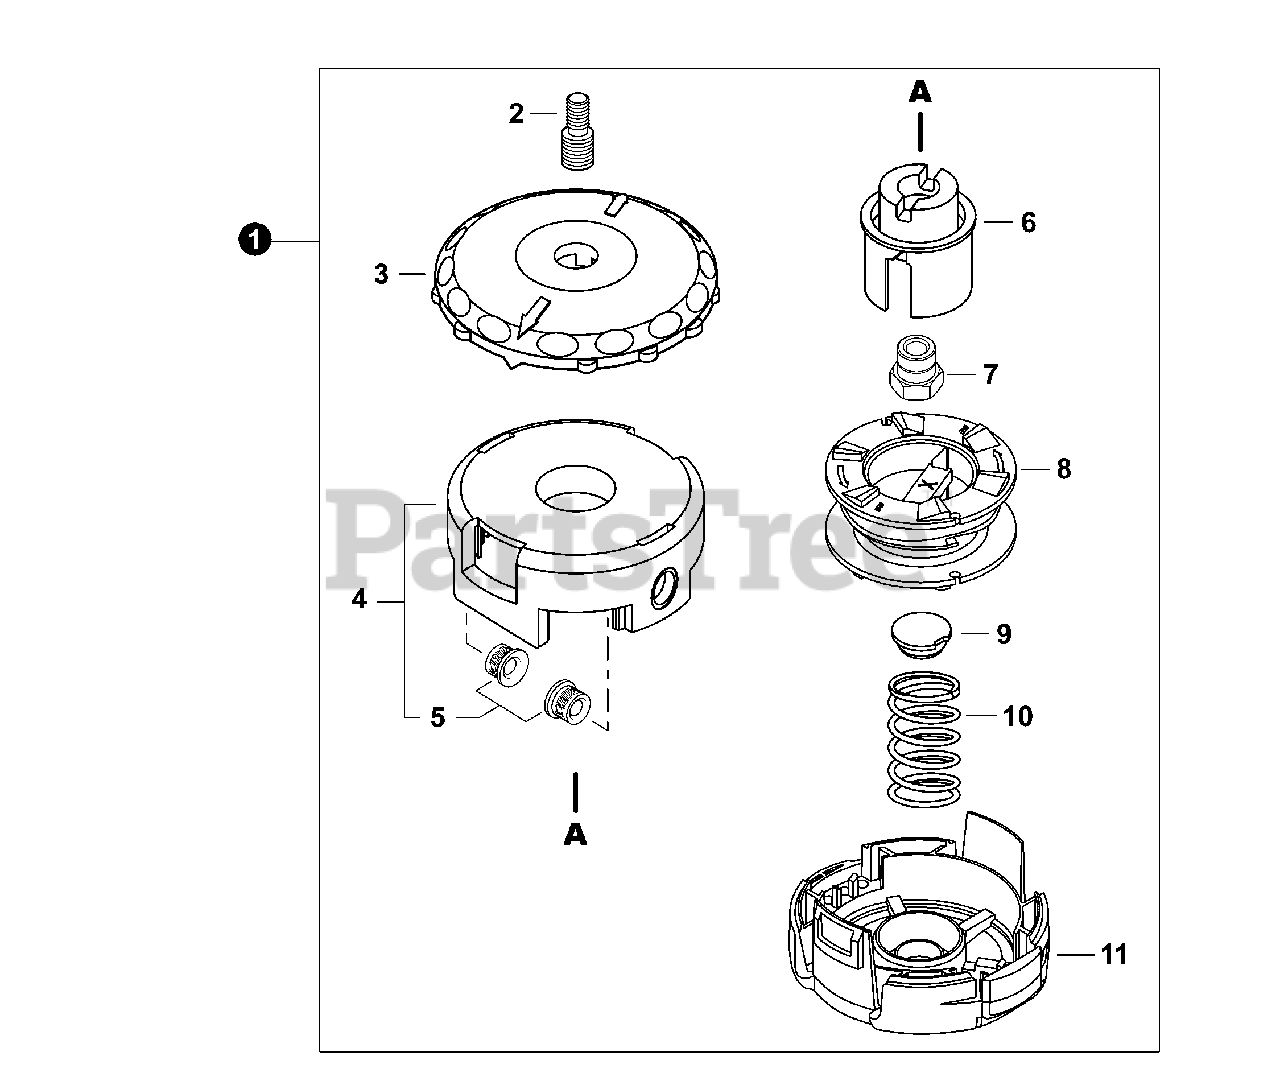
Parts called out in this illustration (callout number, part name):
1	TRIMMER HEAD, SPEED-FEED 400
2	BOLT, STUD M7 x 1.00 /M10 x 1.25 LH GOLD
4	HOUSING ASSY, SPOOL
6	HUB (LH) BLACK
7	BUSHING M10×1.25 LH GOLD
9	CAP, SPRING
10	SPRING, GOLD
11	COVER, SPOOL
